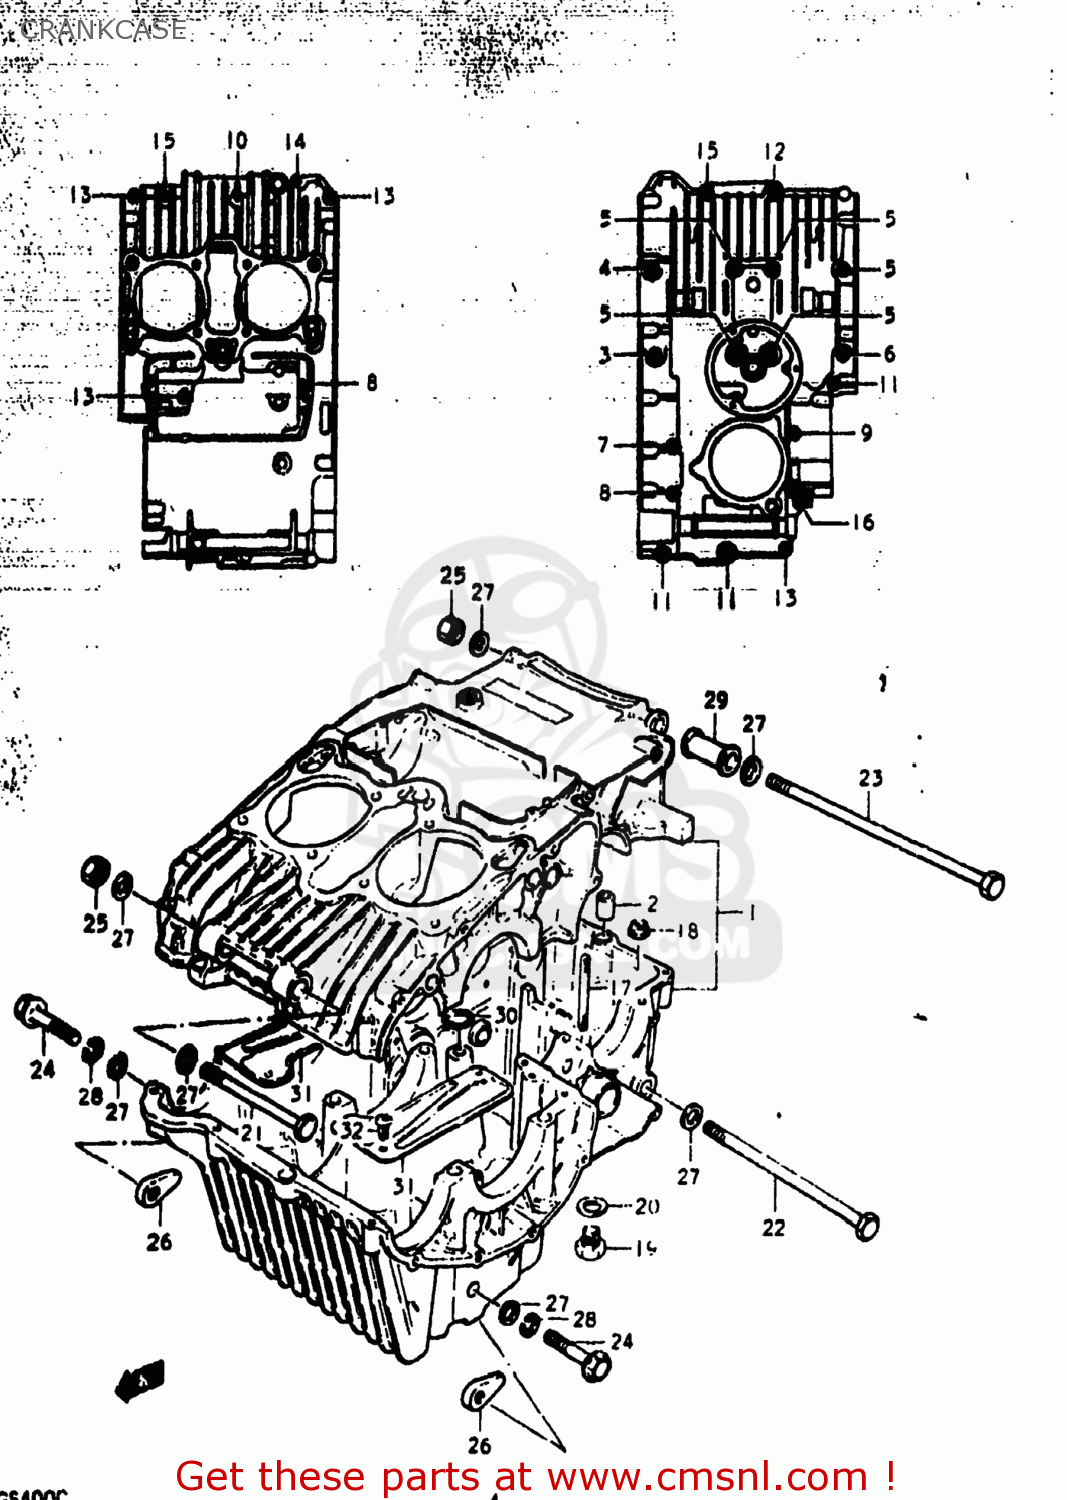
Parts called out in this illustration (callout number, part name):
1	CRANKCASE SET
2	PIN
3	BOLT
4	BOLT (8X95)
5	BOLT 8X90
6	BOLT
7	BOLT
8	BOLT (6X90)
9	BOLT (6X70)
10	BOLT 6X65
11	BOLT (6X60)
12	BOLT,UNDER
13	BOLT
14	BOLT 6X35
15	BOLT
16	BOLT (8X45)
17	STUD BOLT
18	NUT
19	PLUG
20	GASKET(14X19.2X2) (NAS)
21	BOLT
22	BOLT 10X160
23	BOLT 10X265
24	BOLT 10X45
25	NUT
26	NUT
27	WASHER
28	LOCK WASHER
29	SPACER
30	O-RING
31	PLATE,OIL SEPARATOR
32	SCREW
